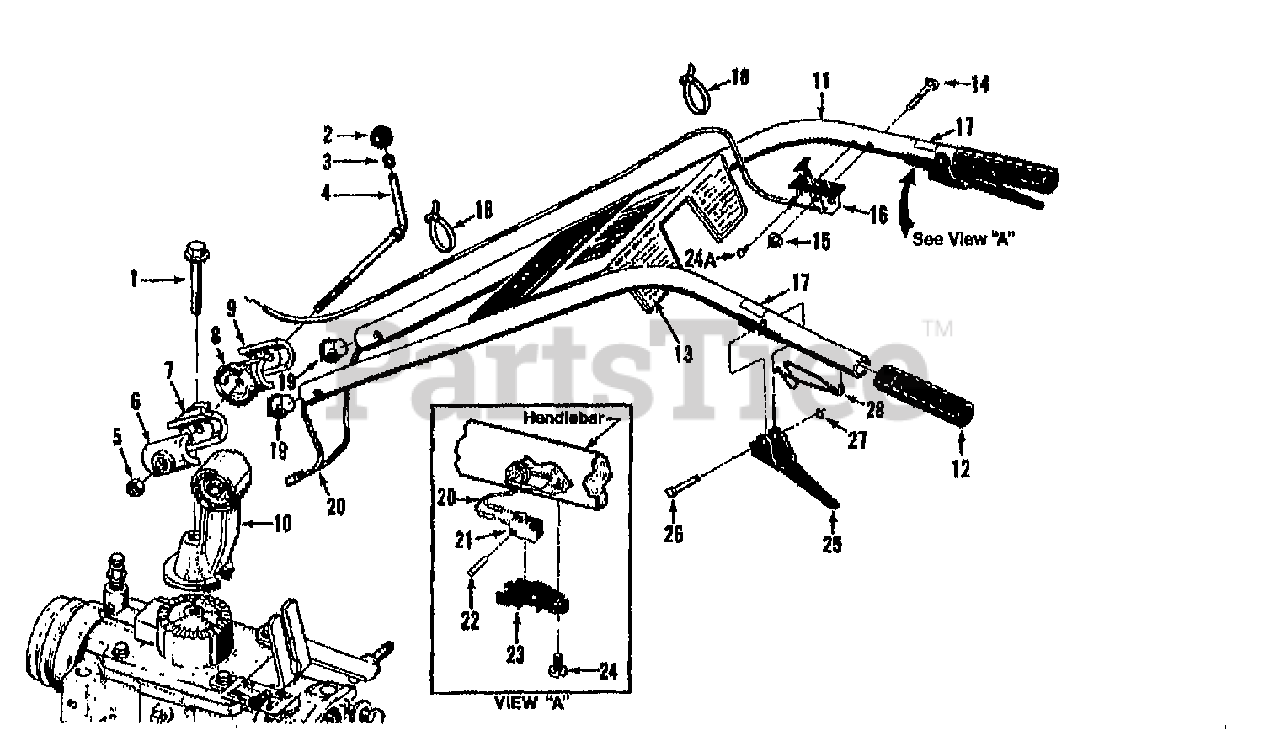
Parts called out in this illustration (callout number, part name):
1	BOLT 1/2-13X3.5 FH GR5
2	KNOB-CONTROL (INCL. 3)
3	RING-TOLERANCE .5325 ID
4	STUD-H/BAR W/NUT & RING (INCL. 2,3 & 5)
5	NUT-HEX JAM 1/2-13
6	CLAMP-LH HORSE 1021-1
7	RATCHET-H/BAR RED 2542-1
8	RATCHET-RH RED HORSE 2542-2
9	CLAMP-RH HORSE 1021-2
10	BASE-H/BAR RED 2534A
11	ASSM-HANDLEBAR W/GRIPS (INCL. 2 OF EA. 12, 17 & 28 AND ONE 13)
12	GRIP-H/BAR SMOOTH
13	DECAL-CONTROL PANEL HORSE
13	DECAL-CONTROL PANEL (11HP)
14	BOLT-CH 1/4-20X2.00 ZP
15	NUT-HF/LK 1/4-20 ZP
16	CABLE-THROTTLE 7 I/C B&S {12068/069/080/081/087}
16	CABLE-THROTTLE 7&8 B&S {12074/075/088/089/090}
16	CABLE-THROTTLE 8HP OPC {12070/071/082/083}
17	DECAL-FWD INTERLOCK
18	TIE-RED
19	RETAINER-HARNESS H/B OPC
20	HARNESS-WIRE OPC HORSE
21	SWITCH-H/B OPC
22	PIN-LK .11X.58 HORSE OPC
23	HOUSING-SWITCH OPC
24	SCR-HW M10-24X.5 STH ZP
24A	SCR-PHS M10-32X.5 STH ZP
25	LEVER-HORSE OPC
26	PIN-PIVOT OPC LEVER
27	RING-KLIP 5304-25
28	SPRING-H/B LEVER
